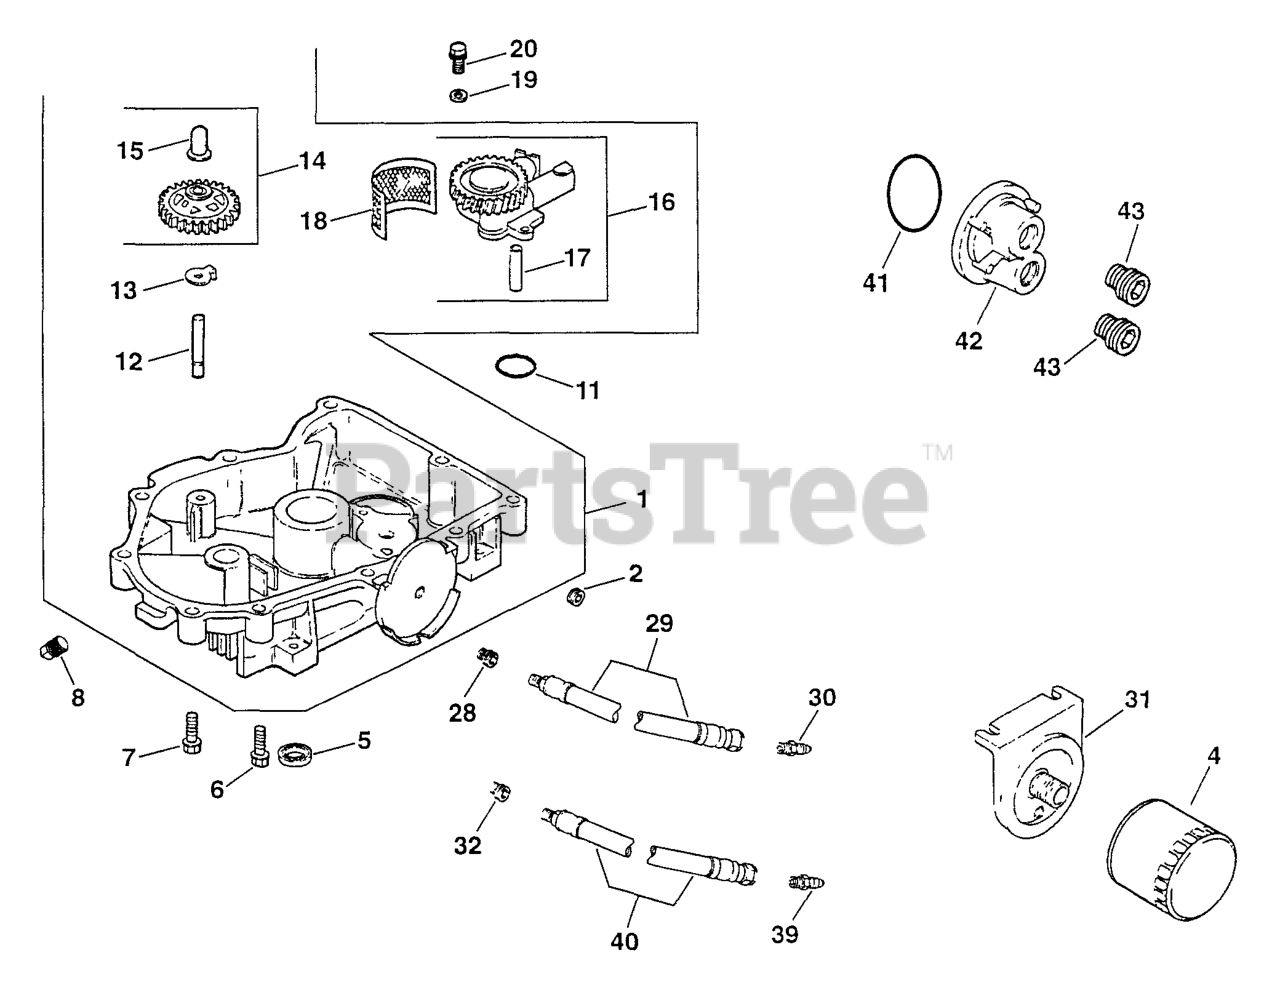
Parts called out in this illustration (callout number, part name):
1	OIL PAN ASSEMBLY - USE 24 199 32-S
2	PLUG, PIPE CTSK 3/8" USE 25 139 62-S
4	OIL FILTER
5	SEAL, OIL (KM)-USE 25 032 06-S
6	SCREW, FLG M8X1.25X45
7	SCREW, HEX FLANGE -USE 24 086 17-S
8	PLUG, SQ HD PIPE 3/8" USE 25 139 57-S
12	SHAFT, GOVERNOR GEAR
14	KIT, GOVERNOR GEAR W/PIN
15	PIN, GOVERNOR REGULATING
16	PUMP, OIL-DISCONTINUED
18	SCREEN - USE 25 162 07
19	WASHER - USE M-631005
20	SCREW - USE M-645025
28	BUSHING, REDUCING-USE 25 158 18-S
29	HOSE
30	NIPPLE
32	BUSHING, REDUCING
39	CONNECTOR
40	HOSE - (#DSC)
